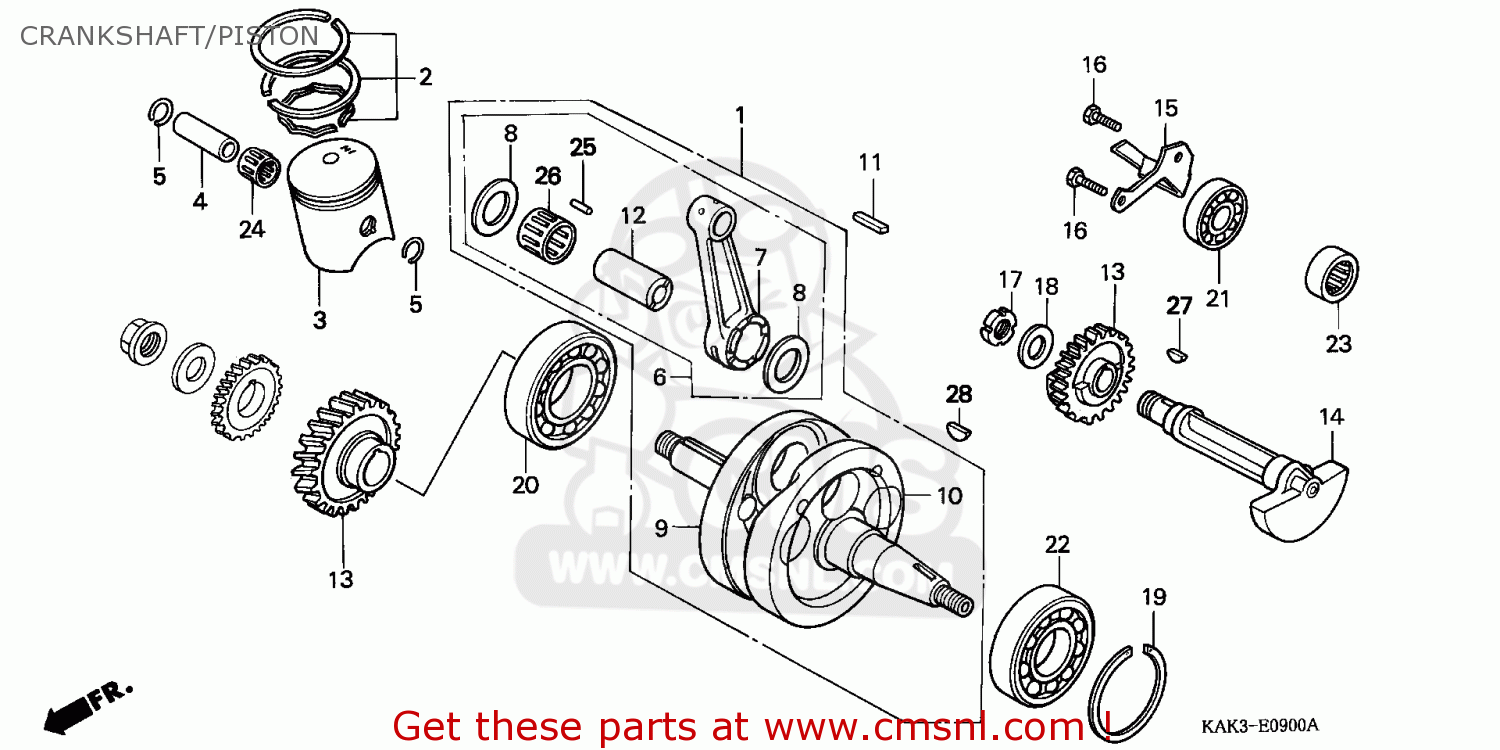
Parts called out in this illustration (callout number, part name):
1	CRANKSHAFT COMP.
2	RING SET,PISTON (
3	PISTON A
5	CLIP,PISON,PIN
6	CONN.ROD ASSY
7	ROD,CONNECTING
8	PLATE,CONNECTING
9	CRANKSHAFT COMP.,
10	CRANKSHAFT COMP.,
11	KEY,6X6X25
12	PIN COMP.A,CRANKS
13	GEAR SET,BALANCER
14	SHAFT,BALANCER
15	PLATE,OIL GUIDE
16	BOLT,HEX.,6X16
17	NUT,LOCK,14MM
18	WASHER,14MM
19	SET,RING
20	BRG.BALL RADIAL,6
21	BEARING,SPECIAL R
22	BRG,BALL RADIAL 6
23	BRG,NDL.24X36X14
24	BRG,CON-ROD S-END
25	ROLLAR A (RED) (0-0.002)
26	RETAINER,CON-ROD
27	KEY, WOODRUFF
28	KEY, WOODRUFF
